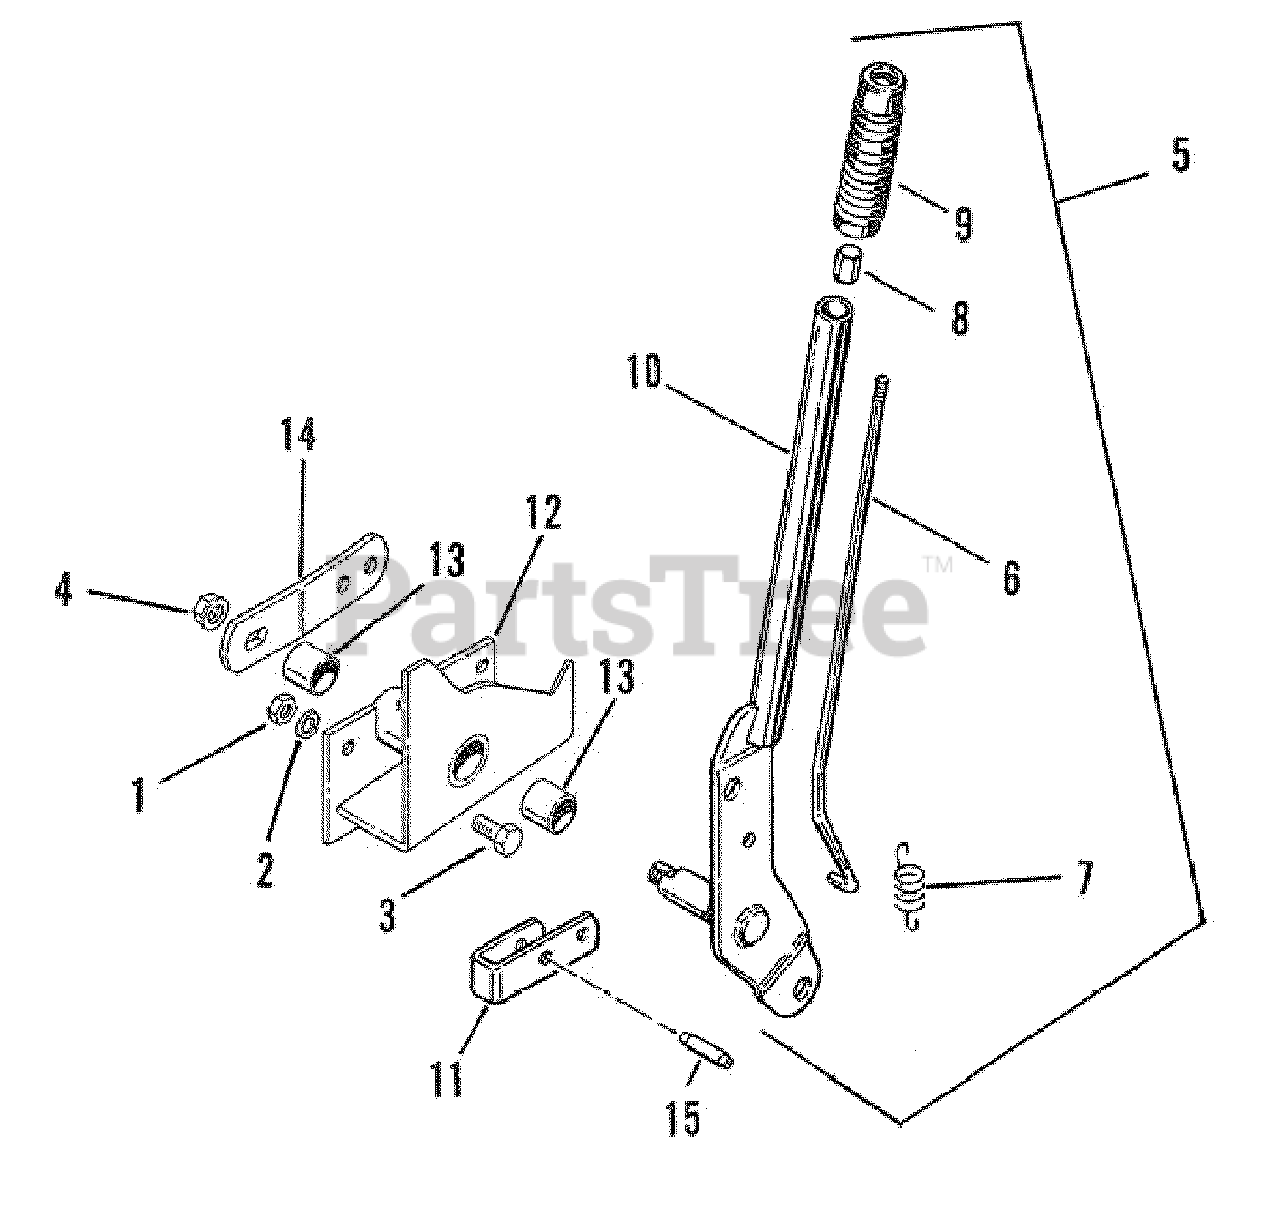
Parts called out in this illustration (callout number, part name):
1	NUT, Hex, Full, 3/8-16
2	LOCKWASHER, 3/8
3	CAPSCREW, Hex, 3/8-16 x 7/8
4	NUT, Flange, 1/2-13
5	LIFT LEVER ASSEMBLY
6	ROD, Latch
9	GRIP, Lift Lever
10	LEVER, Lift
11	LATCH, Lift Lever
12	QUADRANT, Lift Assembly
14	LINK, Lift Lever
15	PIN, Roll, 3/8 x 1
